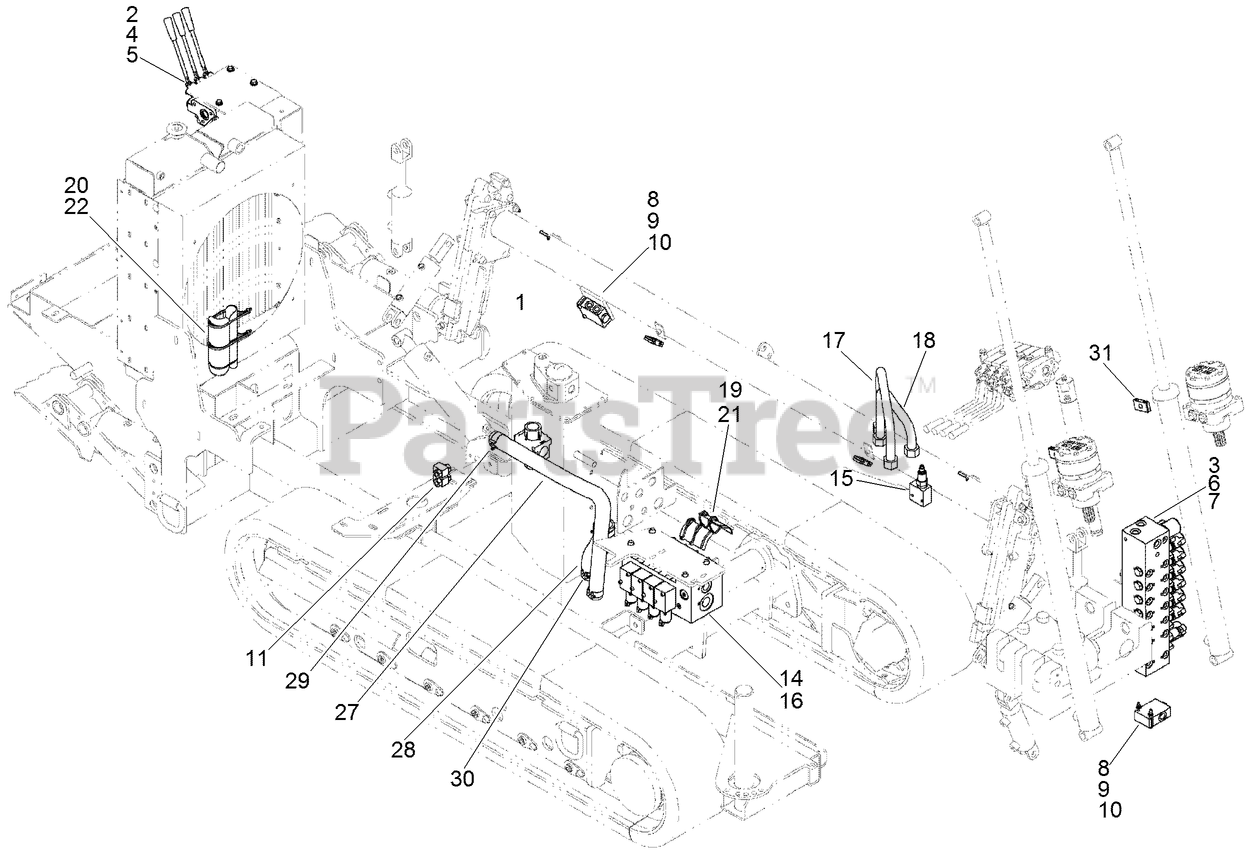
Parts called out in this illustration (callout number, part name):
1	VALVE-THERMOSTAT
2	3 SPOOL HYD VALVE ASM
3	9 SECTION HYD VALVE ASM
4	WASHER-FLAT
5	BOLT
6	WASHER-0.406 x 0.812 x 0.065 in CST ZND
7	SCREW-HH
8	HYD FLOW DIVIDER VALVE ASM
9	SCREW-FLANGE, METRIC
10	NUT, METRIC FLANGE PREVAILING - M6 Zinc
11	VALVE-SHUTTLE, LOAD
14	VALVE - Hydraulic 4 Section
15	PRESSURE RELIEF VALVE ASM
16	SCREW, METRIC FLANGE w/BODY - M8 x 20
17	TUBE-HYD, HIFLOW (ROTARY B)
18	TUBE-HYD, HIFLOW (ROTARY A)
19	PROTECTOR-HOSE
20	PROTECTOR-HOSE, 8 INCH
21	STRAP-TIE
22	STRAP-TIE
30	CLAMP, T-BOLT
31	CLAMP-HALF (SET OF 2)
